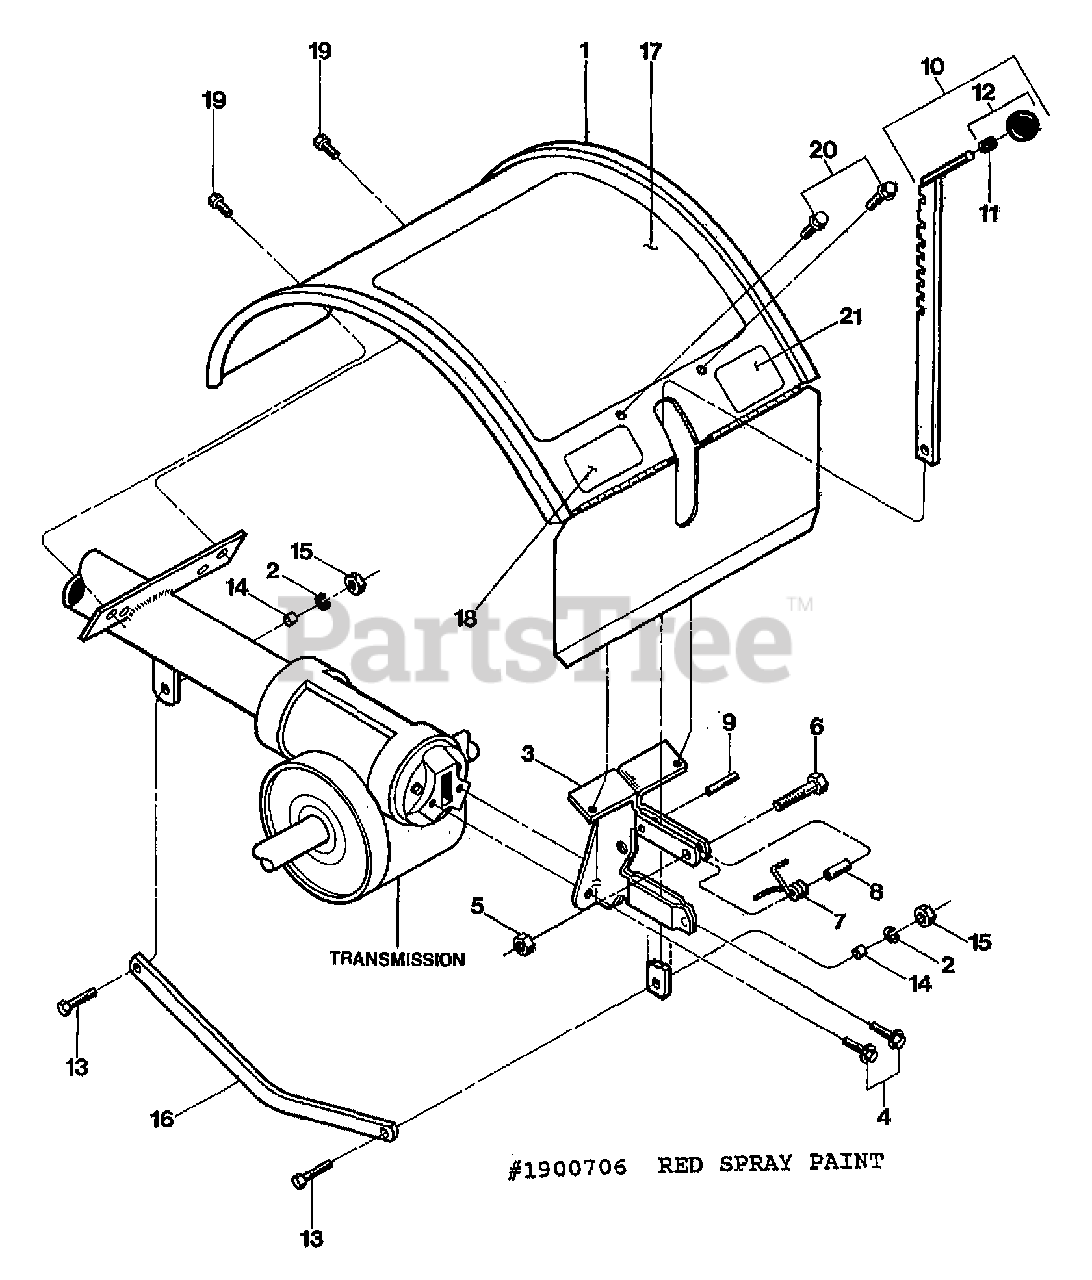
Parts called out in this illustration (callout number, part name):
1	HOOD W/DECALS PONY OPC (INCL. 17, 18 & 21)
2	WASHER-LK .375 @ DEPL
3	BRKT W/ROLL PIN (9308)(INCL. 9)
4	SCR-HFLK 5/16-18X.75 ZP
5	NUT-LK 1/4-20
6	SCR-HH 1/4-20X1.0
7	SPRING-TORSION
8	SPACER-.250X.343X.375
9	PIN-ROLL .25 X 1 (SPIRAL)
10	DEPTH REGULATOR W/KNOB (INCL. 11 & 12)
11	RING-TOLERANCE .5325 ID
12	KNOB-CONTROL (INCL. 11)
13	SCR-HH 3/8-16X1.25
14	BUSHING-.5X.375X.3
15	NUT-HEX 3/8-16 ZP
16	DRAG BAR-BENT
17	DECAL-HOOD OPER INST OPC
18	DECAL-HOOD LOGO PONY OPC (MODEL NAME DECAL)
19	SCR-HWH 5/16-18 X .5 STH
20	SCR-HWH 1/4-20 X .5 STH
21	DECAL-TINE WARN SM FRAME
